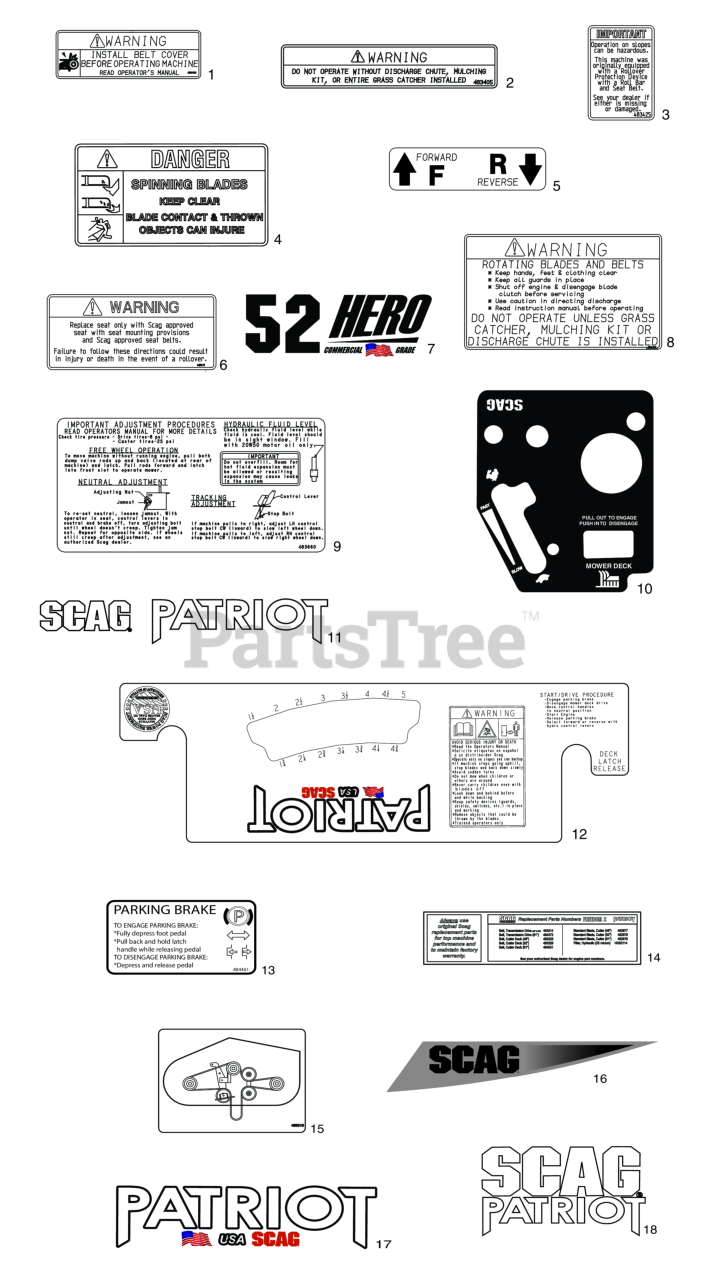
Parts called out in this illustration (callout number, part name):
1	Decal, Warning - Belt Cover
2	Decal, Warning-Discharge
3	Decal, ROPS
4	Decal, Spinning Blades
5	Decal, Traction Control
6	Decal, Seat Replacement
7	Decal, 52H Commercial
8	Decal, Warning - Rotating Blades
9	Decal, Adjustment SFZ
10	Decal, Instrument Panel
11	Decal, Scag RH Fuel Tank
12	Decal, Cutting Height, (Scag Gold Logo)
13	Decal, Brake
14	Decal, SFZ / SPZ Replacement Parts
15	Decal, SZL / SFZ / SPZ Belt Routing
16	Decal, Scag - Fuel Tank
17	Decal, Patriot, (Scag Gold Logo) - Fuel Tank
18	Decal, Scag Patriot, (Scag Gold Logo) - Fuel Tank
